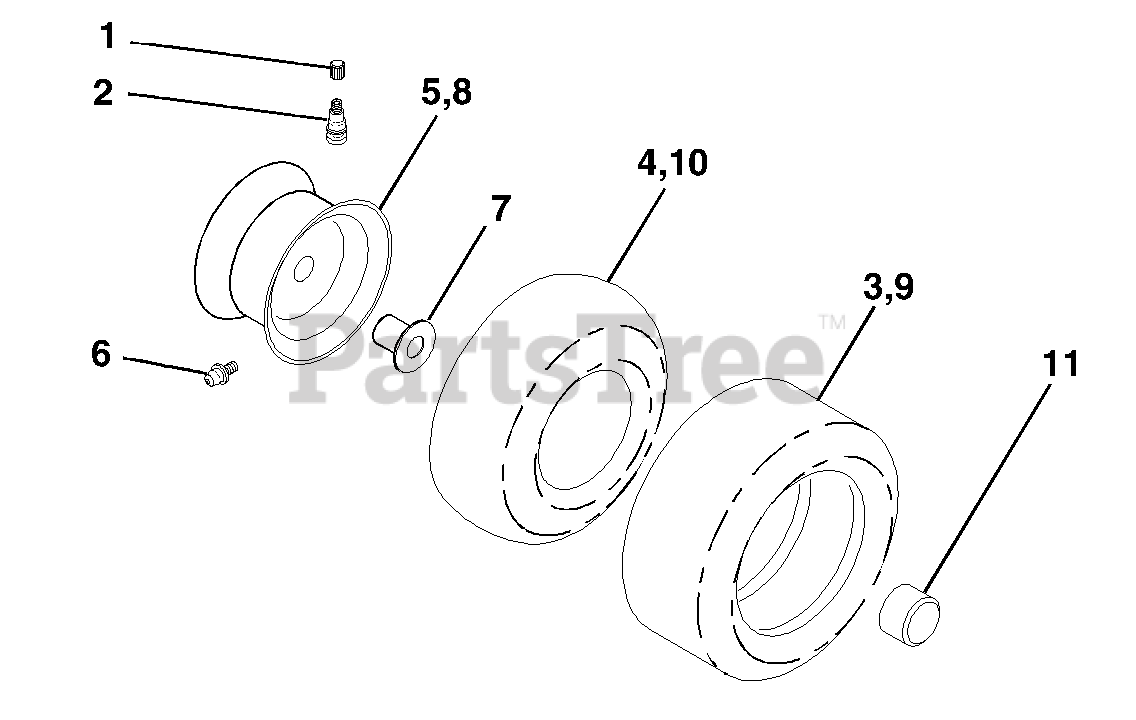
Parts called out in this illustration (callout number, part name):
1	Cap Valve Tire
2	Stem Valve
3	Tire F Ts 15 X 6 0 - 6 Service
4	Tube Front
5	Rim Asm 6"front White Service
6	Fitting Grease
7	Bearing Flange
8	Rim Asm 8"rear White Service
9	Tire R Ts 18x9.5-8 C Service
10	Tube Rear
11	Cap Axle Blk 1 50 X 1 00
